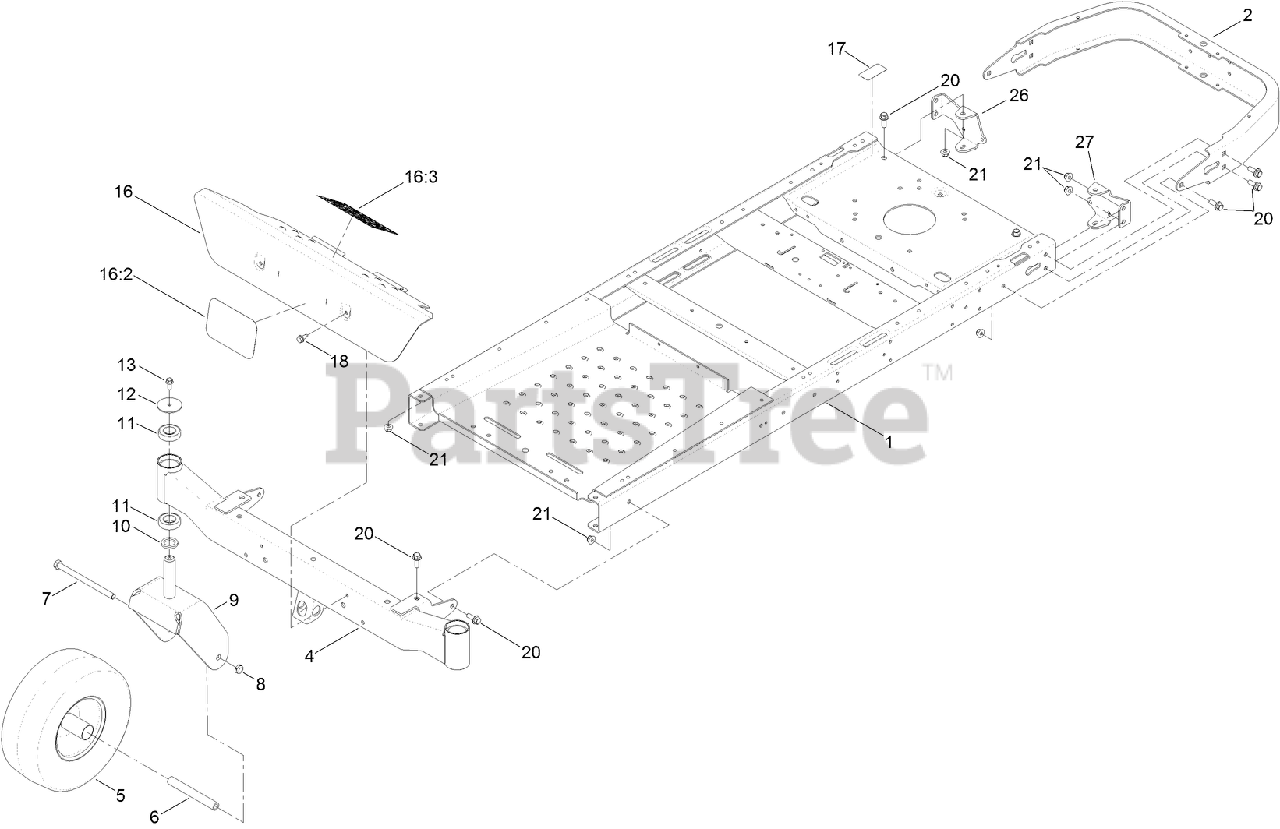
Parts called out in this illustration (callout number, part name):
2	BUMPER-REAR (WIDE)
4	AXLE-FRONT, WIDE
5	13 INCH WHEEL AND TIRE ASM
6	SPANNER
7	SCREW-HH
8	NUT-HEX
9	FORK-CASTER
10	WASHER-THRUST
11	BEARING-BALL
12	WASHER
13	SCREW-HHF
16	FOOTREST ASM
16:2	DECAL
17	DECAL-BYPASS
18	SCREW-HWHTF
20	SCREW-HHF
21	NUT-HF, NI
26	MOUNT-HYDRO, REAR (RH)
27	MOUNT-HYDRO, REAR (LH)
